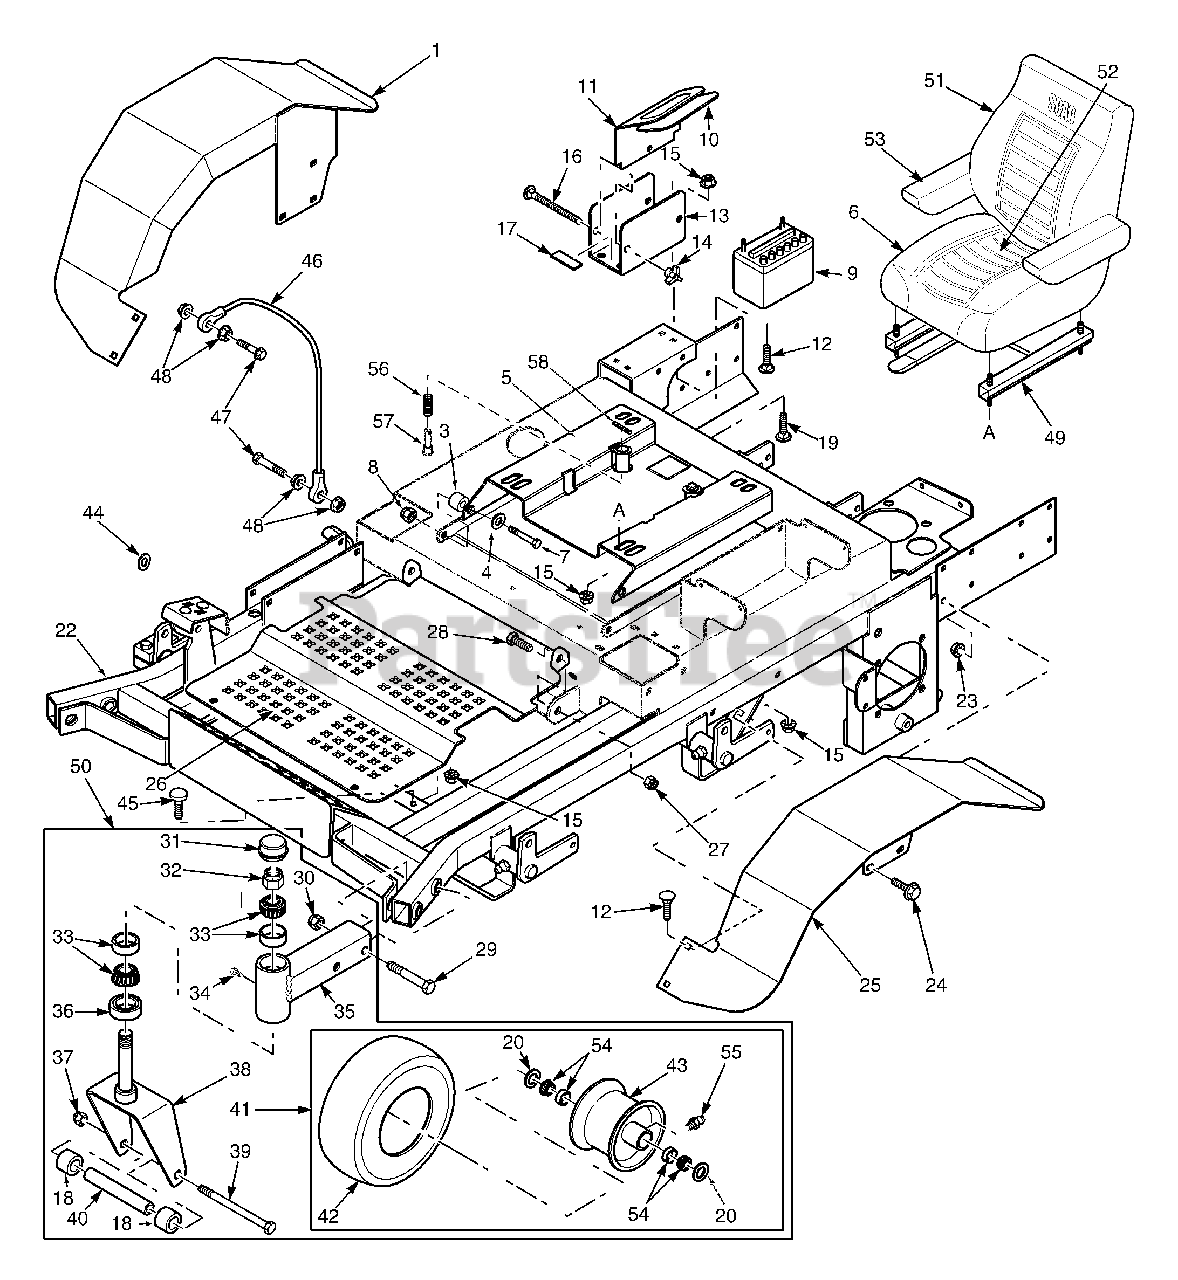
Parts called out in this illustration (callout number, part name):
1	Fender Weldment, RH
3	Spacer
4	Flatwasher, 3/8-.391 x .938 x .105
5	Seat Plate Weldment
6	Seat Assembly w/armrest
7	Bolt, Hex Head 3/8-16 x 2.0"
8	Nut, Elastic Stop 3/8-16
9	Battery
10	Pad, Battery Cover
11	Cover, Battery
12	Bolt, Carriage 5/16-18 x 3/4"
13	Plate, Battery Box
14	Wing Nut, 1/4-20 x 3/4"
15	Nut, Hex Serrated Flange 5/16-18
16	Bolt, Carriage 1/4-20 x 6"
17	Rubber Pad
18	Spacer, Caster Wheel
19	Bolt, Carriage 5/16-18 x 1"
22	Main Frame
23	Nut, Hex Serrated Flange 3/8-16
24	Screw, Hex Serrated Flange 3/8-16 x 1"
25	Fender Weldment, LH
26	Foot Plate
27	Nut, Hex Elastic Stop 3/8-16
28	Bolt, Hex Head 3/8-16 x 1"
29	Bolt, Hex Head 5/8-11 x 4"
30	Nut, Hex Elastic Stop 5/8-11
31	Cap, Grease
32	Nut, Hex Elastic Stop 1.0-14
33	Bearing W/Race
34	Plug, 1/4-28 THD Form
35	Extension Weldment, Caster 52A (LH)
36	Seal, 2.00 OD. x 1.625 Bore
37	Nut, Hex Elastic Stop 1/2-13
38	Yoke Weldment, Caster (52A)
39	Bolt, Hex Head 1/2-13 x 7-1/2" (52A)
40	Sleeve, Caster Wheel (52A)
41	Wheel Assy, 52A
42	Tire, 13 x 5.00 4-Ply (52A)
43	Rim Assembly, 52A
44	Flatwasher, 3/8"-.391 x .938 x .105
45	Bumper, Rubber
46	Cable, Seat Stop
47	Bolt, Hex Head 1/4-20 x 1-1/4"
48	Nut, Hex Serrated Flange 1/4-20
49	Seat Adjustment, Track Set
50	Caster Wheel Assy 52A (RH)
51	Back Cushion Cover
52	Seat Cushion Cover
53	Arm Rest, Right Hand
54	Bearing w/ Race
55	Grease Fitting
56	Spring, Seat
57	Pin Retainer, Spring
58	Roll Pin, Spring 5/32 x 3/4"
